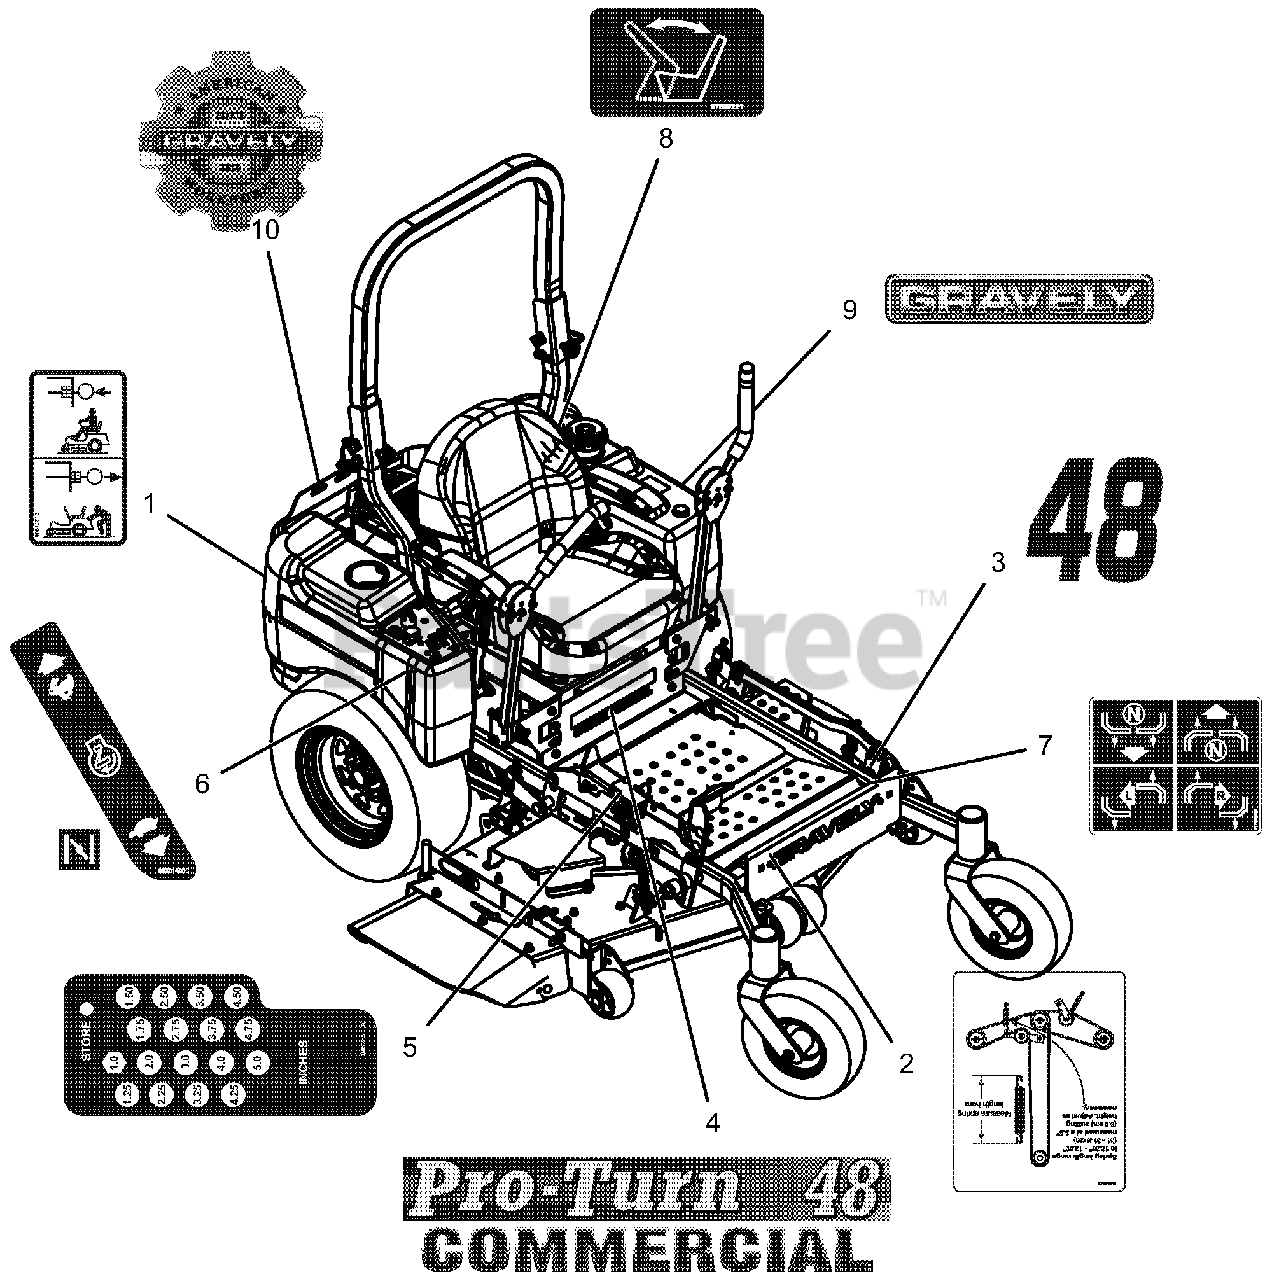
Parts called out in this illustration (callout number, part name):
1	DECAL, TRANSMISSION DISCONNECT
2	DECAL, BELT ROUTING
3	DECAL, 48"
4	DECAL, 48" PRO-TURN
5	DECAL, HEIGHT OF CUT
6	DECAL, SPEED CONTROL
7	DECAL, INSTRUCTIONAL - STEERING
8	DECAL, SEAT RELEASE
9	DECAL, FUEL TANK-GRAVELY
10	DECAL, GRAVELY HERITAGE-LARGE
